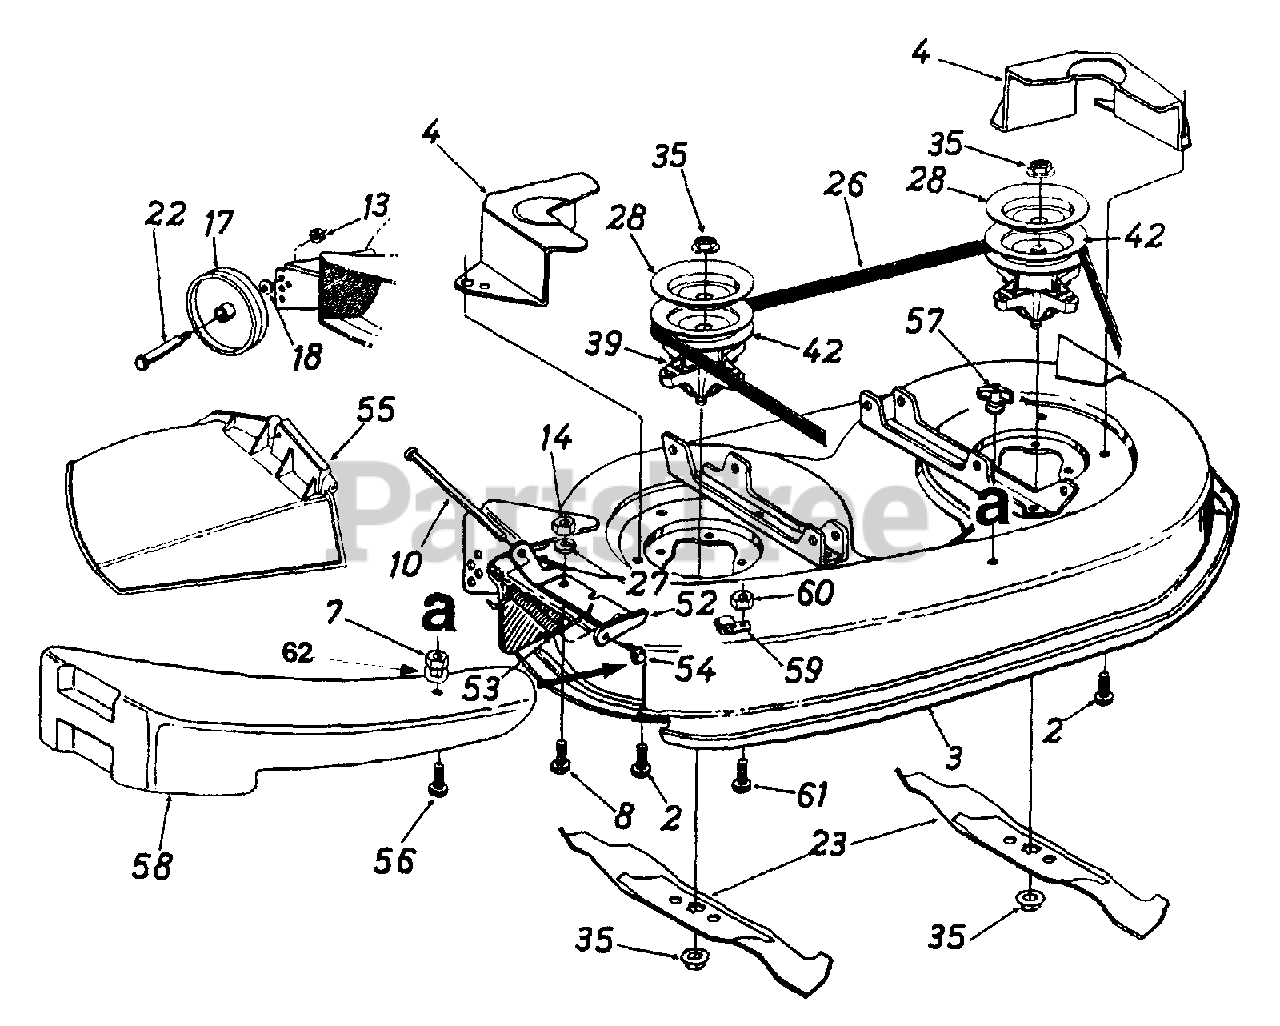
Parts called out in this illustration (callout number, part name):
2	Hex Wash. TT-Tap Scr. 5/16-18 x .75"
7	Hex L-Nut 1/4-20 Thd.
8	Hex Bolt 1/4-20 x .62"
10	Hinge Pin
13	Hex Top L-Nut 3/8-16 Thd.
14	Hex Nut 1/4-20 Thd. (Gr. 5)
17	Deck Wheel - 5"
18	Bell-Wash. .40" I.D. x .88" O.D.
22	Shld. Bolt .498" Dia. x 1.53"
23	3 in 1 Blade
26	V-Belt
27	Bell-Wash. 1/4" I.D.
28	Brake Disc
35	Hex Flange Nut 5/8-18 Thd.
39	Blade Spdl Ass'y.
42	5" Dia. Pulley
52	Hinge Mtg. Brkt.
53	Torsion Spring
54	Push Nut
55	Chute Ass'y.
56	Hex Bolt 1/4-20 x 1" Lg.
57	Wing Nut 1/4-20 Thd.
58	Mulching Plug
59	Retainer Hook Brkt.
60	Hex Sems Nut 1/4-20 Thd.
61	Hex Bolt 1/4-20 x .62" Lg.
62	Flat Washer .28 ID x .74 OD
